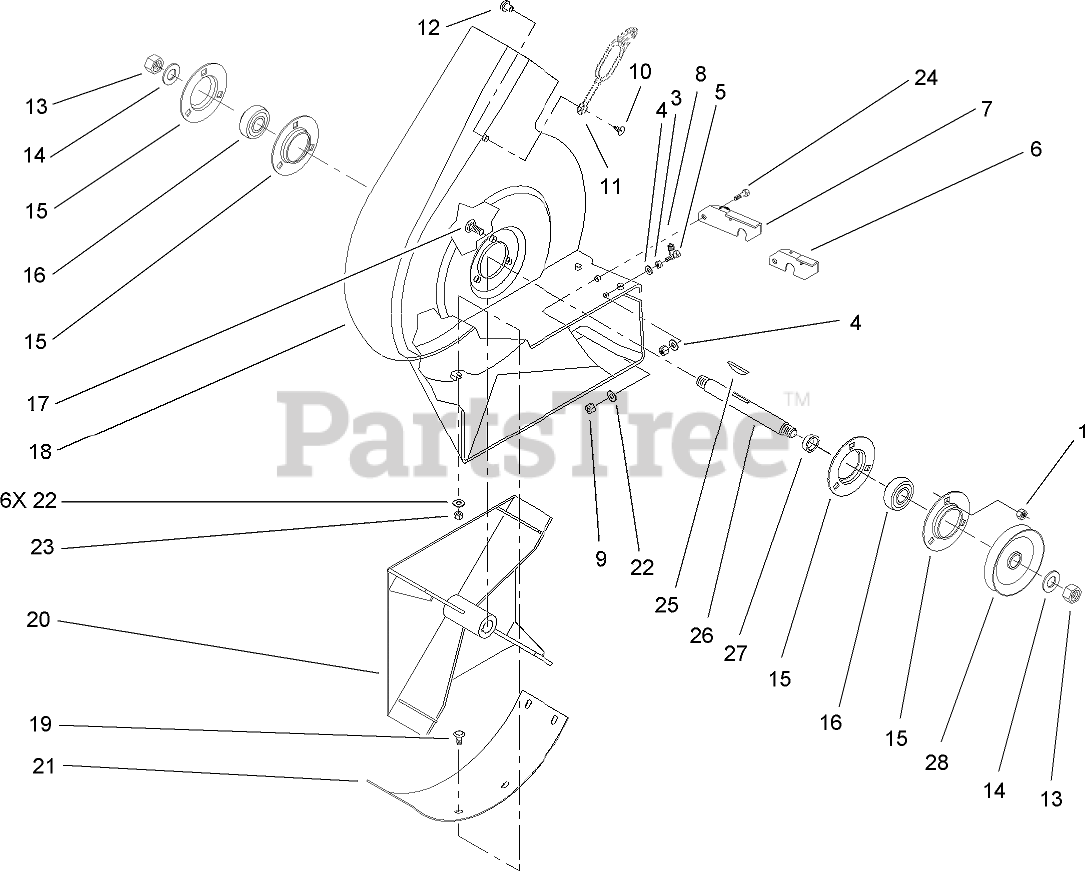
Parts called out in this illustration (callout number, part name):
1	NUT-HF
3	NUT-HEX
4	WASHER-FLAT
5	SCREW-HWH
6	Latch-Blower
7	Latch-Blower
8	SPRING-EXTENSION
9	NUT-LOCK, NI
10	FASTENER-PANEL
11	RETAINER-DUCT
12	SPACER-INTERLOCK
13	NUT-JAM
14	WASHER-LOCK
15	FLANGE
16	BEARING-BALL
17	SCREW-CARR
18	HOUSING-VAC, BLOWER
19	SCREW-CARR
20	IMPELLER ASM
21	Cover-Blower, Bottom
22	WASHER-FLAT
23	NUT-LOCK, NI
24	SCREW-HH
26	SHAFT-BLOWER
27	Spacer
28	PULLEY-BLOWER
